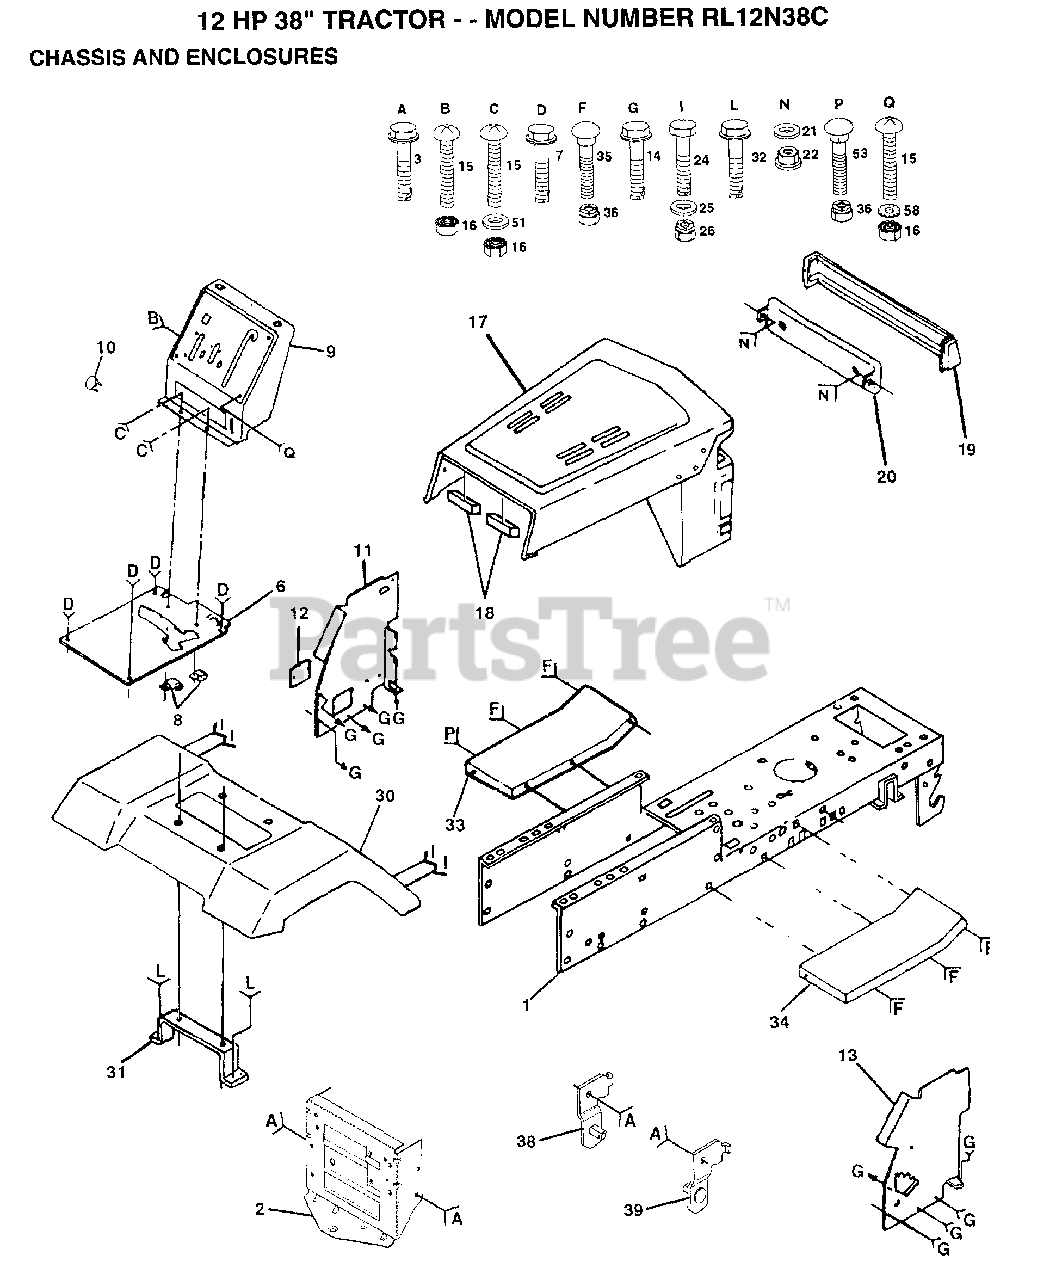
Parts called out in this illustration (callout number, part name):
3	SCREW
7	SCREW
8	CLIP T
9	DASH SILKSCRN 1
10	PLUG BUTTON T
11	PANEL DASH LH
12	COVER ACCESS
14	SCREW LT
15	SCREW
17	HOOD/GRILL ASM
21	WASHER PM
22	PAL NUT LT
24	BOLT
25	WASHER
26	NUT
31	BRKT FENDER
32	SCREW
33	FOOTREST LH
34	FOOTREST
35	BOLT
36	NUT
38	BRACKET ASM LH
39	BRACKET ASM RH
51	WASHER
58	LOCKWASHER
